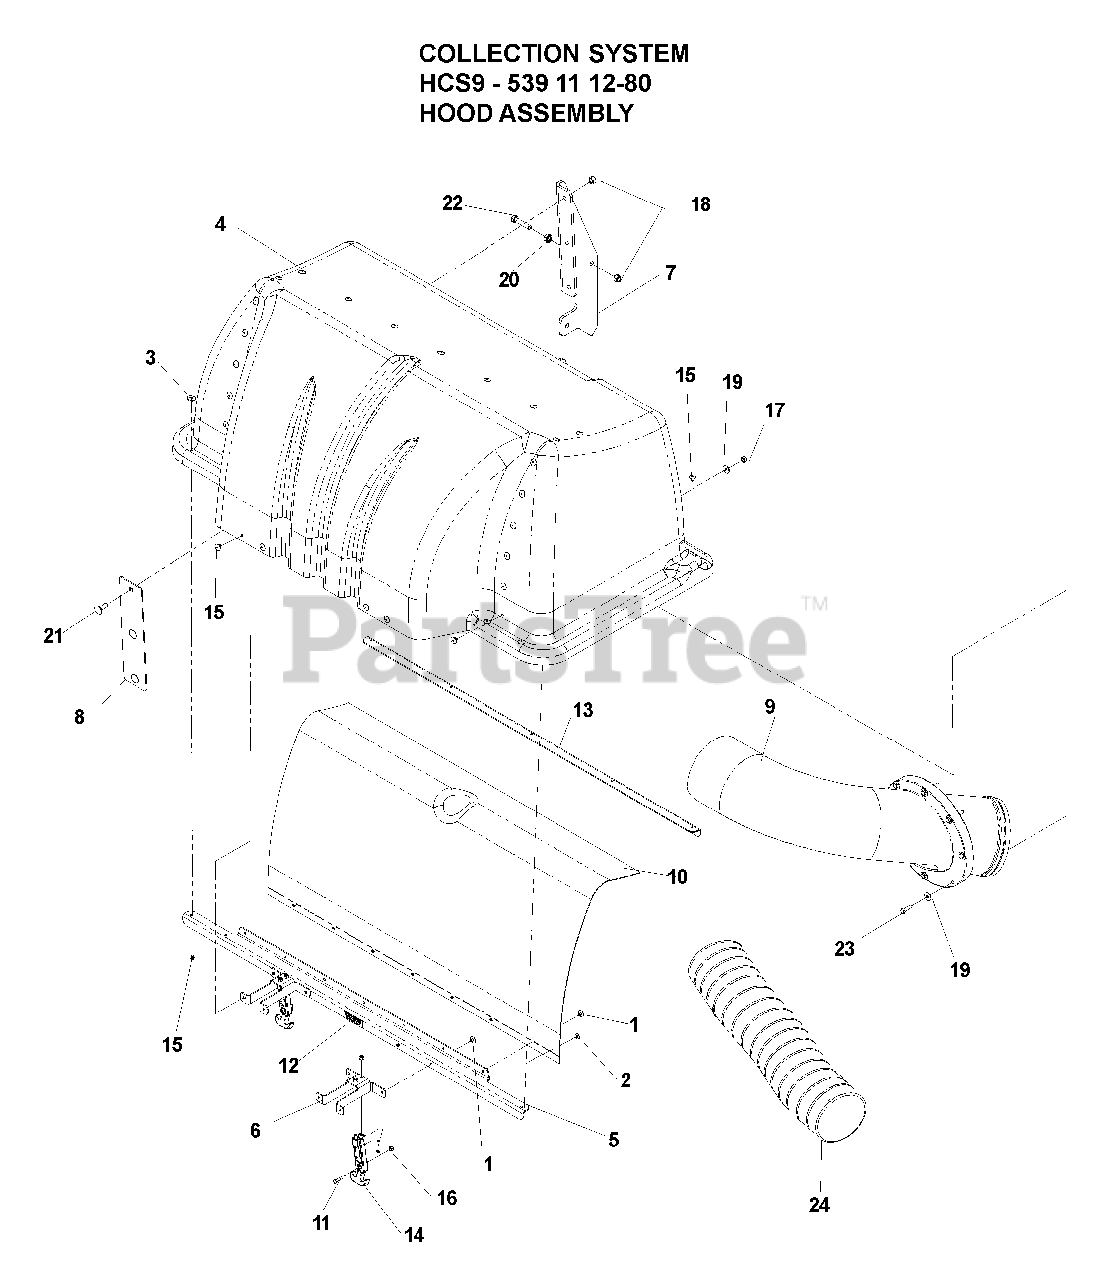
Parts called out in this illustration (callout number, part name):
1	RIVET, 3/16 X 1/4
2	WASHER, #10
3	WASHER, #10, MACH
5	HOOD SUPPORT
6	SUPPORT, DRAW LATCH
7	HOOD HINGE
8	MOUNT PLATE
9	INLET TUBE
10	MESH, POLY DIAMOND
11	SCREW, #10-24 X 1 1/8
12	DECAL, VENTILATION
13	HOOD SUPPORT, REAR
14	DRAW LATCH, T-HANDLE
15	RIVET, 3/16
16	NUT, #10-24, NYLOC
17	NUT, 1/4-20, NYLOC
18	NUT, 3/8-16, NYLOC
19	WASHER, 1/4
20	NUT, 3/8-16, WHIZLK
21	RHSNB, 3/8-16 X 1, GR5
22	HCS, 3/8-16 X 1 3/4, GR5
23	HCS, 1/4-20 X 1 3/4, GR5
539111280	Hood Assembly Collection System (HSC9)
